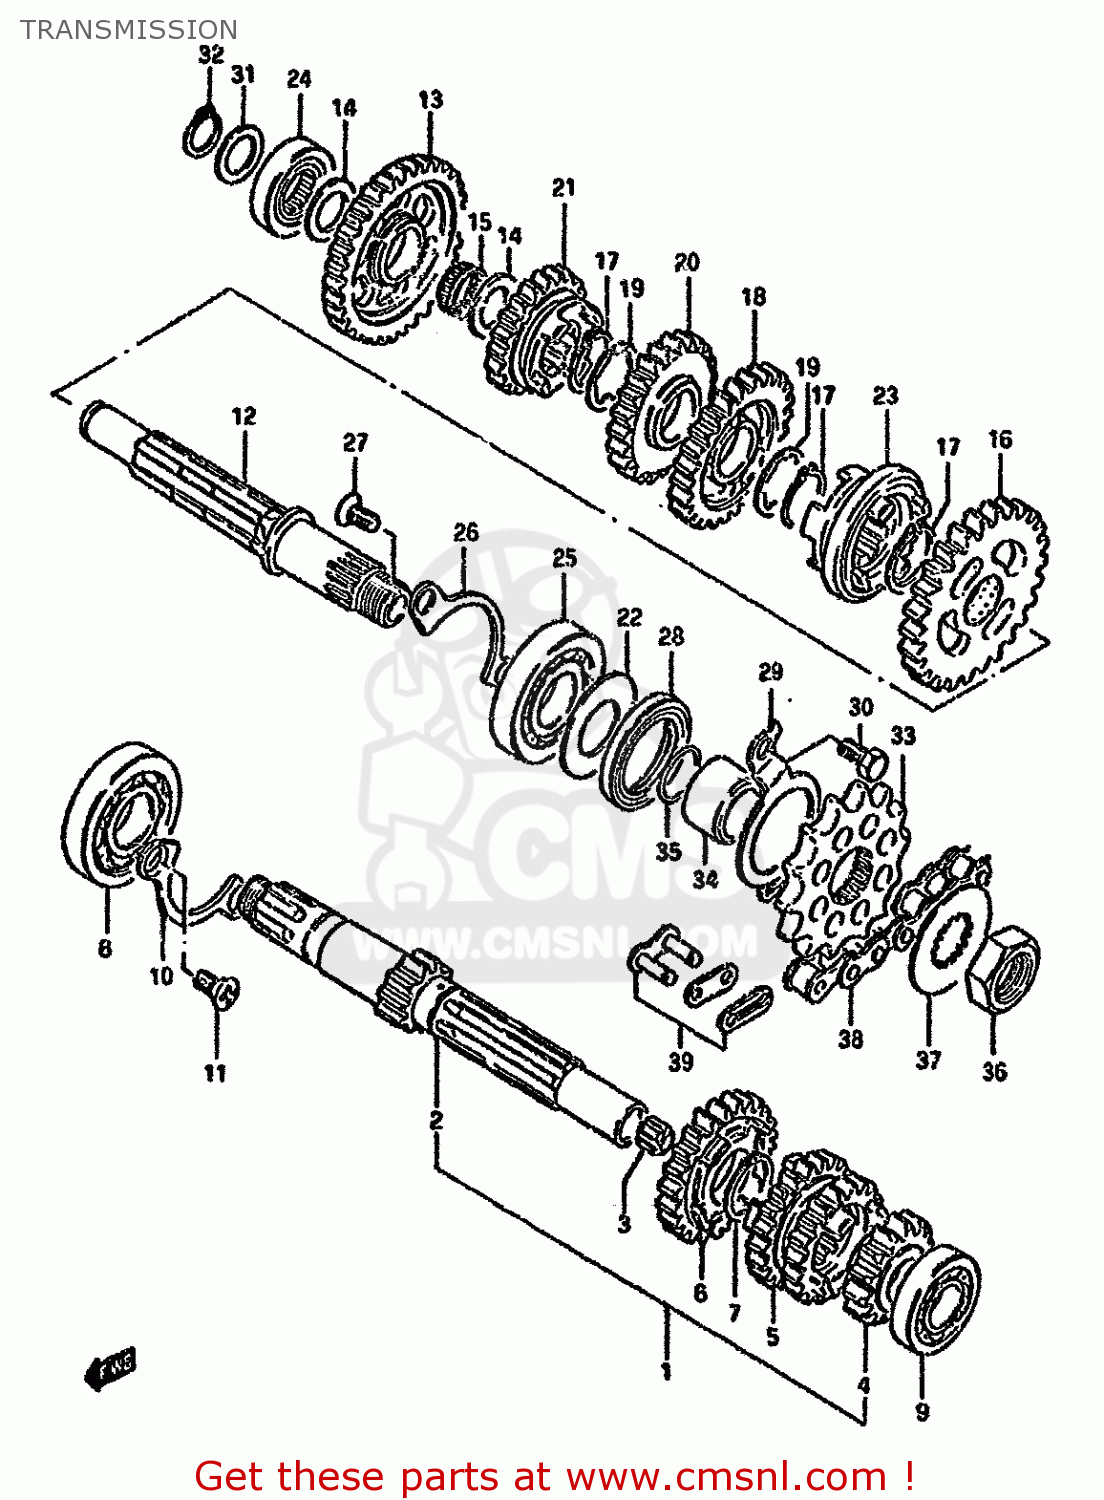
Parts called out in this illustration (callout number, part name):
1	SHAFT,COUNTER
2	SHAFT,COUNTER
3	BUSH
4	GEAR,SECOND DRIVE
5	GEAR,THIRD & FOURTH DRIVE,N
6	GEAR,FIFTH DRIVE
7	CIRCLIP
8	BEARING(20X47X14)
9	BEARING
10	RETAINER,DRIVE SHAFT BEARING
11	SCREW
12	SHAFT,DRIVE
13	GEAR,FIRST DRIVEN
14	WASHER
15	BEARING(15X19X7.8)
16	GEAR,SECOND DRIVEN
17	CIRCLIP
18	GEAR,THIRD DRIVEN
19	WASHER,LOCK
20	GEAR,FOURTH DRIVEN
21	GEAR,FIFTH DRIVEN
22	WASHER,OIL SEALING
23	WHEEL,SLIDING DOG
24	BEARING(15X33X12)
25	BEARING(20X47X14)
26	RETAINER,DRIVE SHAFT BEARING
27	SCREW
28	SEAL,OIL(27X40X6)
29	PLATE,DRIVESHAFT OIL
30	BOLT
31	WASHER
32	CIRCLIP
33	SPROCKET,ENGINE
34	SPACER
35	O RING(D:2.4,ID:19)
36	NUT
37	WASHER,LOCK
38	CHAIN,DRIVE
39	JOINT(RK)
